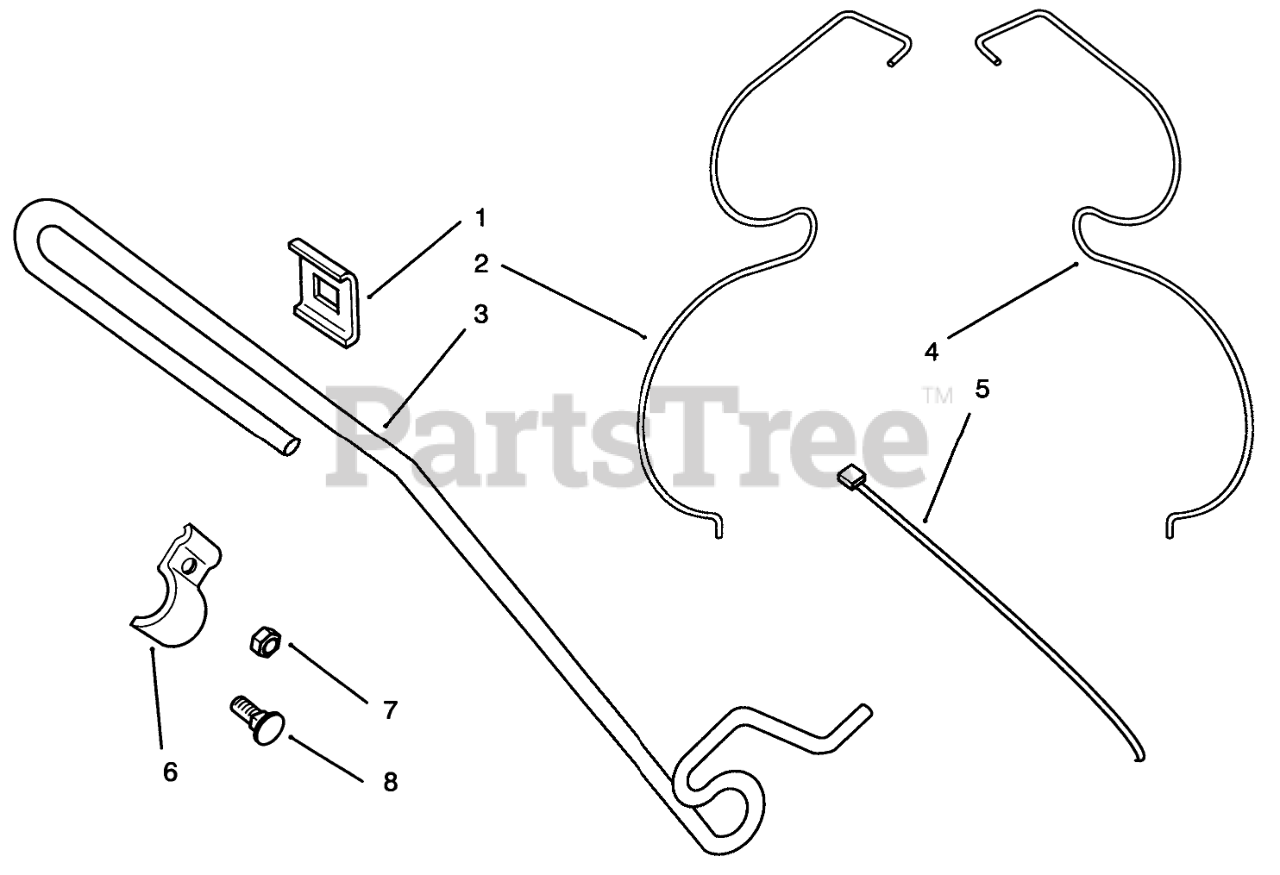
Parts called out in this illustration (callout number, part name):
1	Bracket-Mounting
2	SPRING-LH HOLD DOWN
3	Rod-Hopper Mounting
4	Spring-Hold Down R.H.
5	TIE-CABLE
6	Clamp-Cable
7	NUT-LOCK, NI
8	BOLT-CARR
